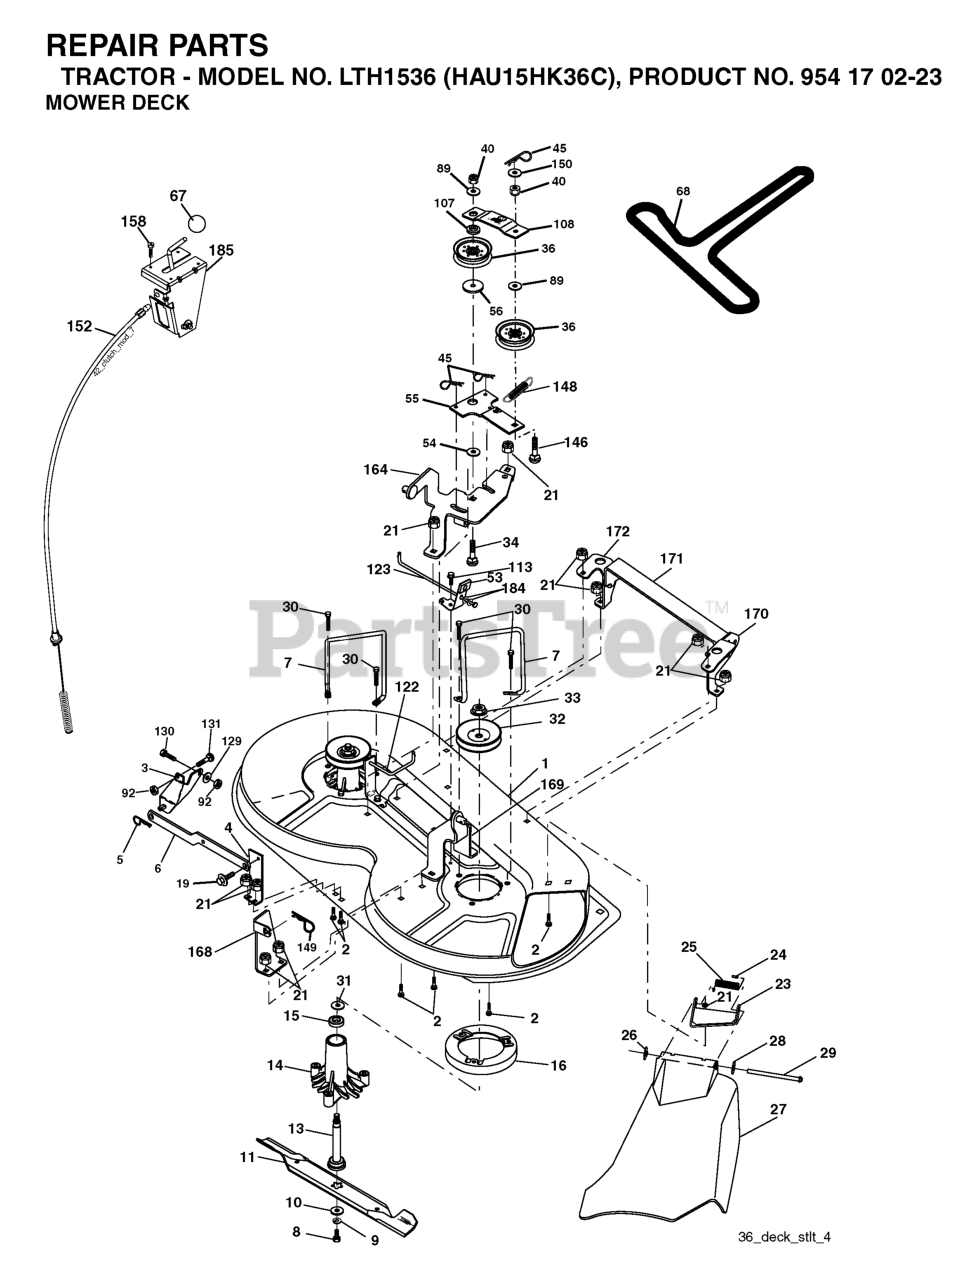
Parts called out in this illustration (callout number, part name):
2	RP BOLT 5/16-18 X3/4 ZN/YEL GR
3	BRKT ASM SWAY BAR
5	RETAINER-SPRNG RB
6	BAR SWAY DECK
8	BLADE BOLT
9	LOCKWASHER
10	WASHER.BLADE
11	BLADE, HI-LIFT 36" PREMIUM
13	SHAFT ASM VENT
14	HOUSING.MANDREL.VENTED (MACHD)
16	STRIPPER.MANDREL.ROUND.BLACK
19	BOLT SHD 5/16-18
21	LOCKNUT
23	BRACKET ASM DEFLECTOR
24	CAP-SLEEVE LT
25	SPRING TORSION
26	NUT PUSH M
27	CONSOLE.STLT.5SP.BLK
28	Washer 11/32 x 5/8 x 16 Ga SD
29	HINGE ROD
30	SCREW, WASHER HEAD
31	WASHER.SPACER.MANDREL
32	PULLEY, MANDREL
33	NUT, FLG TOPLOCK 9/16"
36	FLAT IDLER PULLEY
45	RETAINER M
53	BRAKE ASSEMBLY
56	SPACER.RETAINER.MOWER
67	KNOB T (3/8 HOLE)
89	WASHER
92	NUT
107	SPACER.IDLER.ARM
108	STIFFENER.IDLER.ARM
113	Screw 5/16-18 x 1/2 Hex, Self Tapping 5/16-18 x 1/2
129	WASHER
131	BOLT D
146	BOLT, CARRIAGE IDLER
148	IDLER RETURN SPRING
149	SPRING.RETAINER.YELLOW.ZINC
158	SCREW
171	BRACE.SUPT.SUSP.FRT.CRD
184	WASHER
185	HEAD ASM. CABLE CLUTCH
